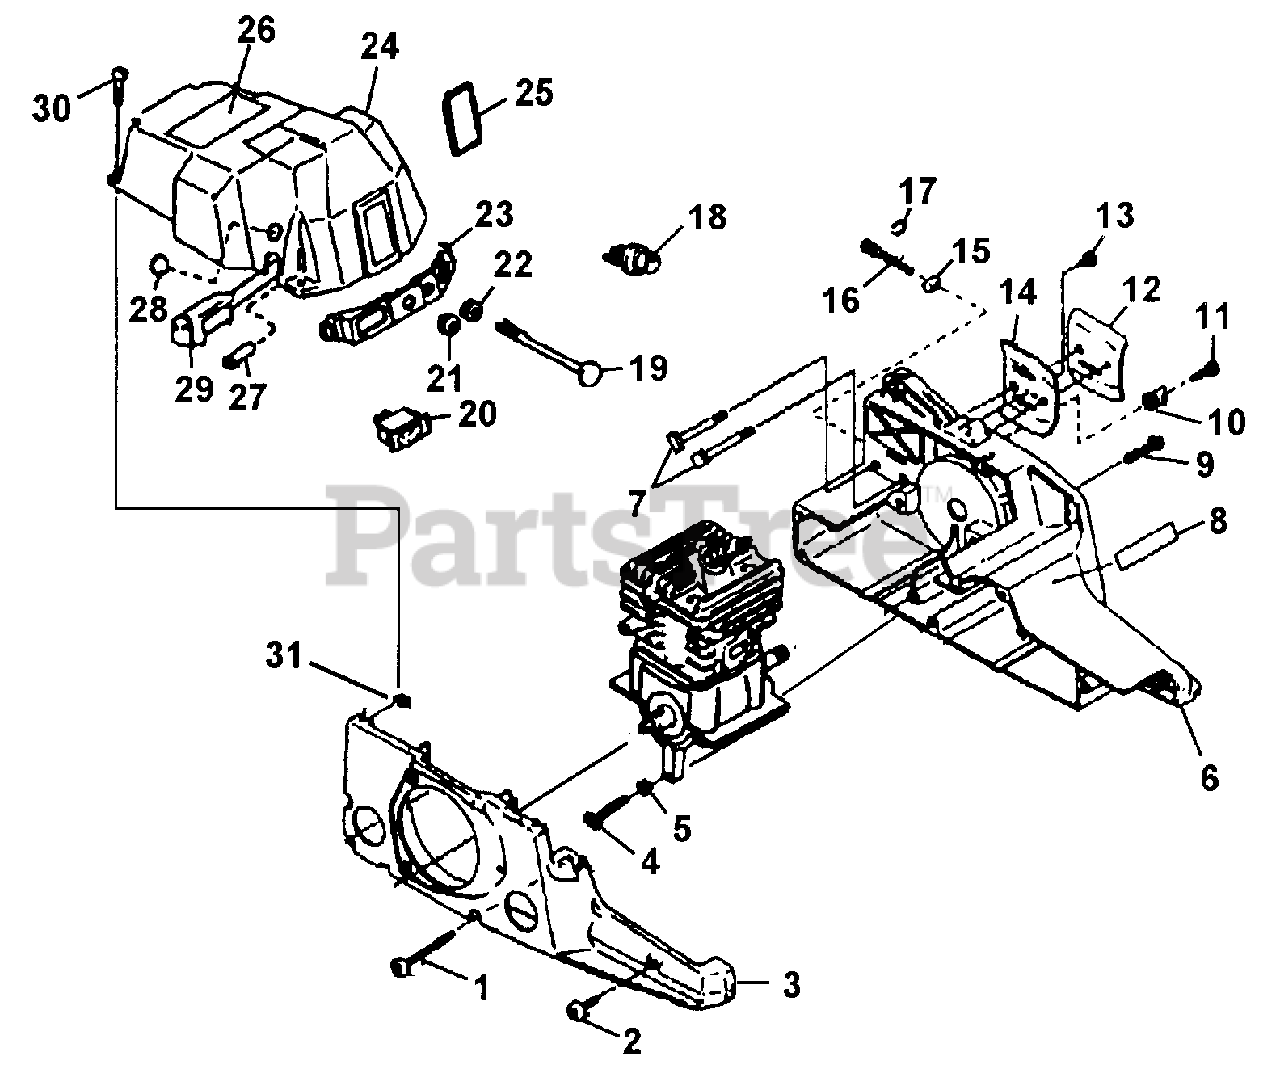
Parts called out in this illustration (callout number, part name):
1	SCREW- Thread Form (8-16 x 1 3/4")
2	SCREW- Thread Form. (8-16 x 5/8")
3	HOUSING-Starter Side
4	SCREW-Thread Form. (10-14 x 1 1/8")
5	WASHER-Lock
6	HOUSING- Drive Side
7	BOLT Guide Bar
8	DECAL- Panel
9	SCREW-Hex Hd. (12-24 x 1")
10	STOP- Chain
11	SCREW- Thread Form (10-14 x 7/8")
12	PLATE- Guide Bar (Outer )
13	SCREW- Thread Form. (6-19 x 1/2")
14	PLATE- Guide Bar (Inner)
15	PIN- Adjusting
16	SCREW- Guide Bar Adjusting
17	RING- Snap
18	BULB- Primer
19	ROD- Choke
20	SWITCH- Ign.
21	BOOT Throttle Cable
22	GROMMET Choke
23	PANEL Control
24	CYLINDER COVER
25	SCREEN- Air Inlet
26	LABEL Warning
27	GROMMET Carburetor
28	PLUG- Idle Speed
29	GROMMET Carburetor
30	SCREW- Round Hd. (10-24 x .710)
31	NUT Square (10-24)
